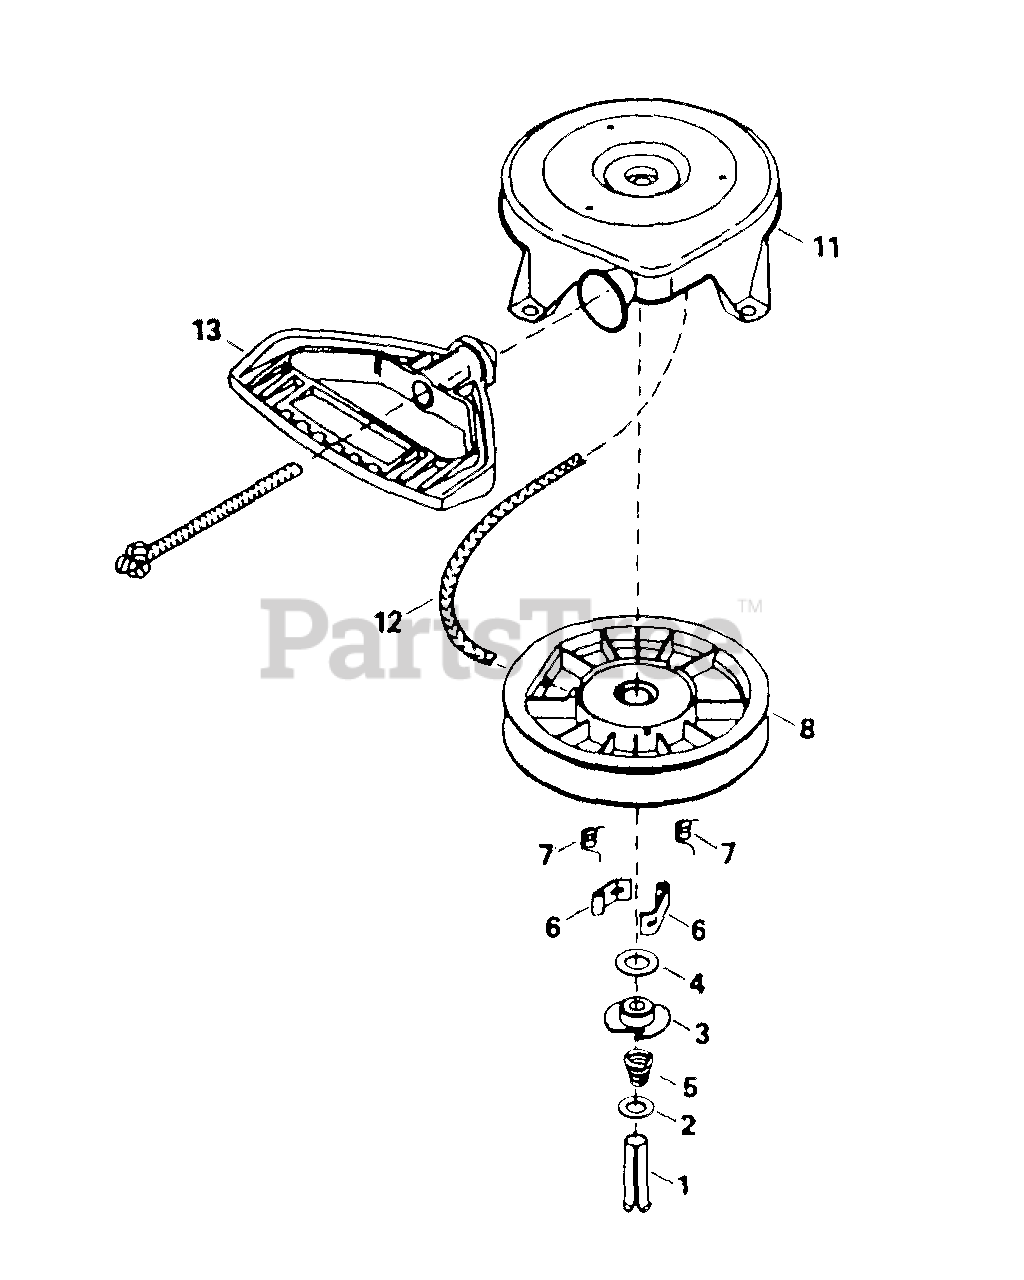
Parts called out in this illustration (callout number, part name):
1	Pin, Spring
5	Spring, Brake
6	Dog, Starter
7	Spring, Dog
8	Pulley & Rewind Spring Ass'y.
11	Housing Ass'y., Starter
12	Rope, Starter (Length 114" & 11/64" Dia.)
13	Handle, Mitten Grip
